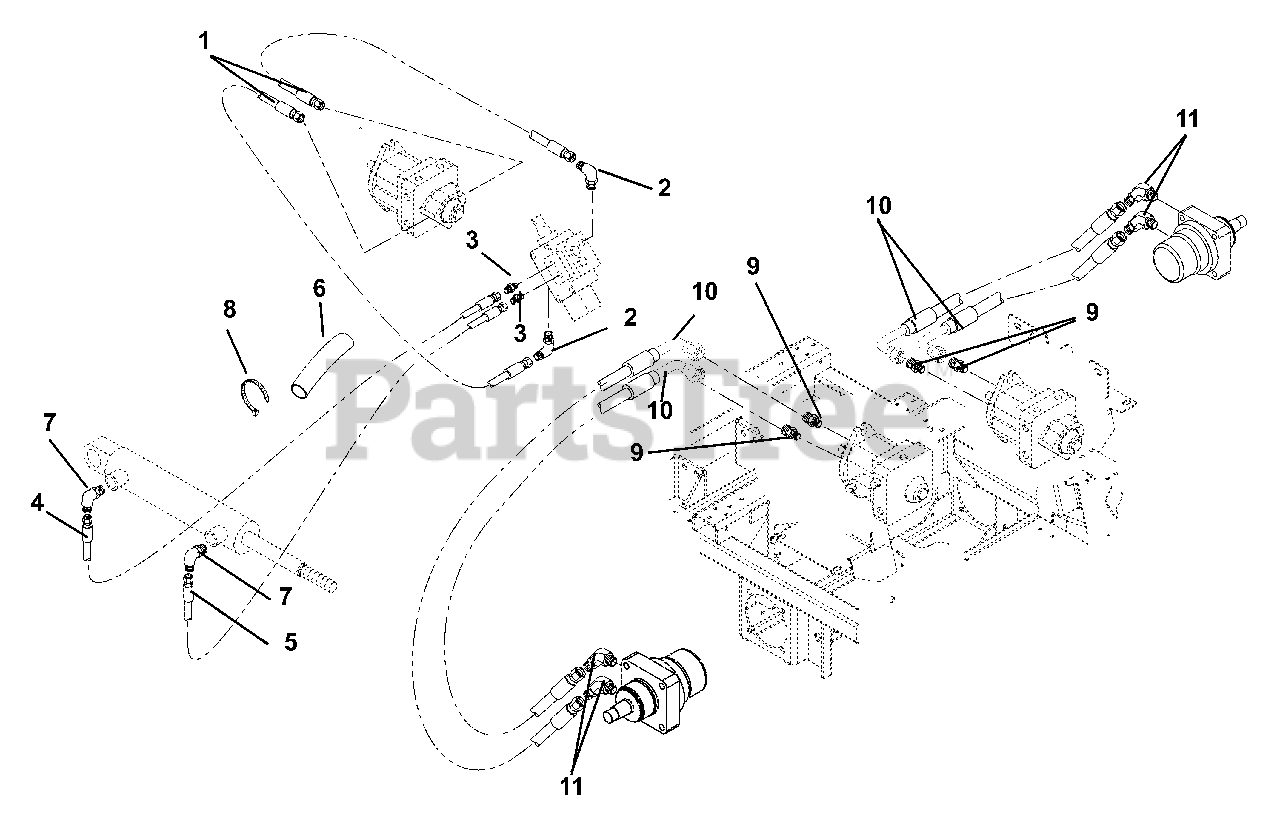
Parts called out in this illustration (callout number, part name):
1	Hose, Hydraulic
2	Hydraulic, Fitting Elbow
4	Hose, Hydraulic
5	Hose, Hydraulic
6	Sleeve Protective 24"
7	Fitting, Hydraulic
8	Cable Tie
9	Adapter, Face Seal 8 x 8 .50 O-Ring
10	Hose, Hydraulic .50
11	Adapter-Hydraulic Steel .875 to .75
